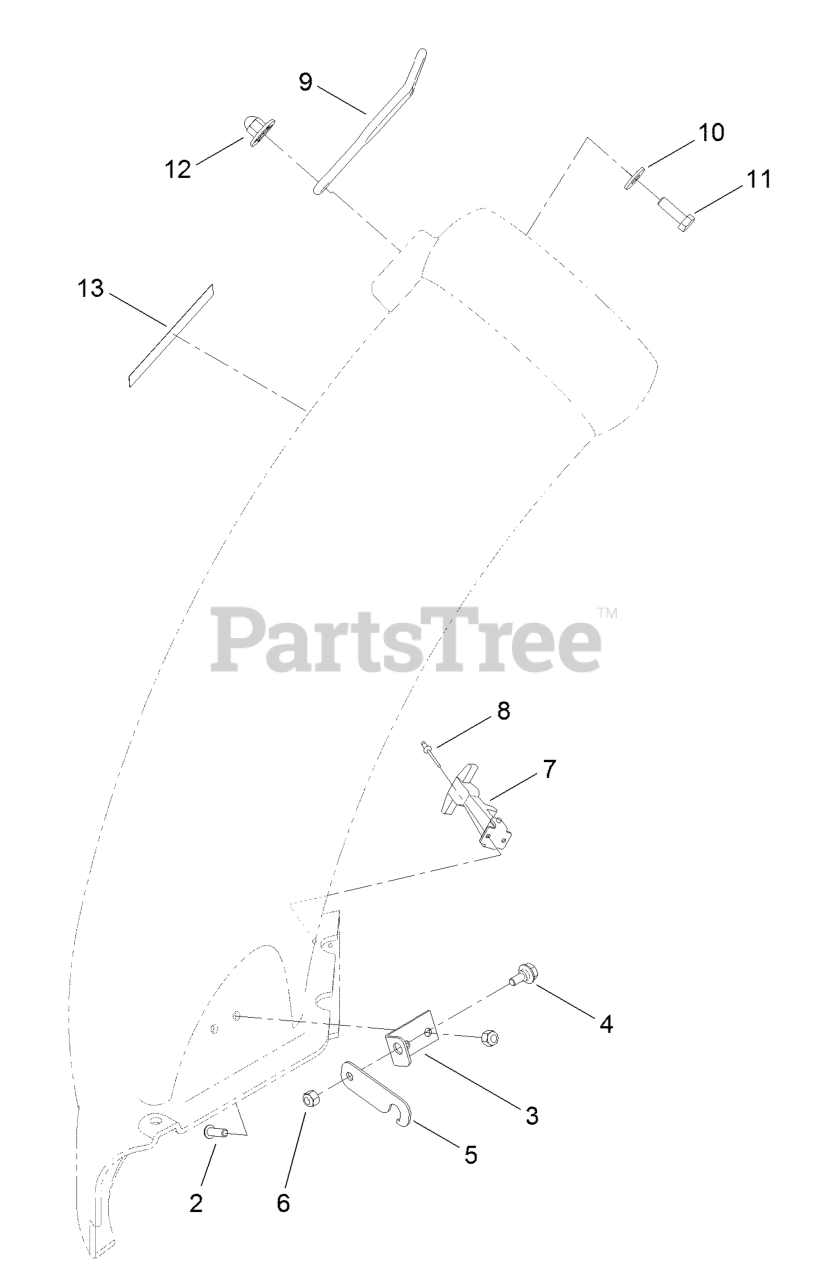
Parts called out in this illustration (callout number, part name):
2	SCREW-HSBH
3	PLATE-PIVOT
4	SCREW-SHOULDER,HWH
6	NUT-LOCK, NI
7	HANDLE ASM
8	RIVET-POP
9	RETAINER-DUCT
10	WASHER-FLAT
11	SCREW-HH
12	NUT-IMPELLER
13	DECAL-DANGER
